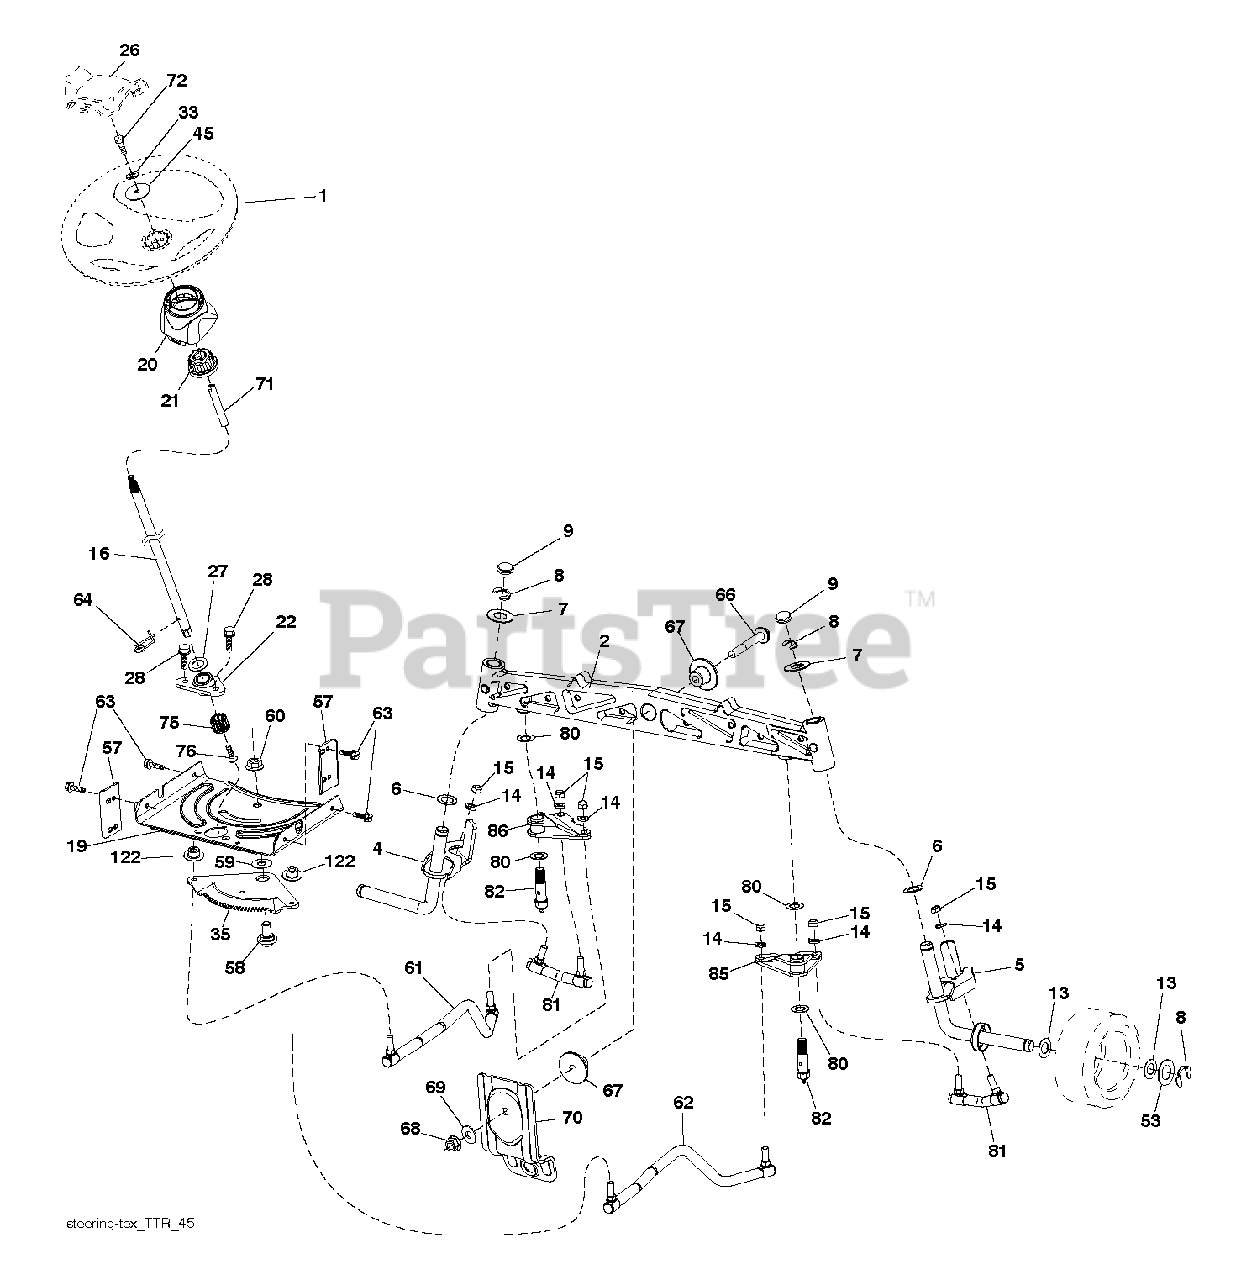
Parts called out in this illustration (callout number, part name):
1	WHEEL.STEER.HUSQ.SR.498.OVMLD
2	AXLE ASSY;TTR;ALUMINUM SILVER
4	SPINDLE WELDMENT.SPINDLE.LH.15
5	SPINDLE WELDMENT.SPINDLE.RH.15
6	THRUST WASHER
9	CAP.SPINDLE.BLACK
14	WASHER, LOCK 3/8
15	NUT CROWNLOCK 3/8-24
16	3 HIGH.SHAFT-ZINC.PLATED
19	PLATE.STEER.DDL.NLT/NG
20	STEERING.BOOT.HUSQ.LT
21	RP STEERING.WHEEL.ADAPTER
22	BEARING.SUBASM.SHAFT.STEER.LOW
26	INSERT.CAP.WHL.STRG.HUSQ.PREM
28	SCREW, 3/8-16X3/4
33	LOCKWASHER
35	GEAR GEAR.SECTOR.TEX.NZTR
45	WASHER.11/32
53	WASHER.HARDENED
57	BRACKET.UPSTOP.TEX
58	BOLT.SHOULDER.SECTOR.P
59	WASHER.THURST.SECTOR.S
60	NUT FLANGE LOCK 5/8-11
61	LINK ASSY DRAGLOINK, ADJUSTABL
62	DRAGLINK,ADJUSTABLE,RH
63	SCREW
64	RETAINER.CLIP.SPRING.S
66	BOLT HEX FGHD 7/16-14 X 3 SERR
67	BUSHING.PM.FRONT AXLE
68	NUT.LOCK.FLANGE.7/16
69	WASHER.1.5X.505X.118
70	BRACKET.FRT.DECK.SUSP.RR.MT431
71	SHAFT.EXTEN.STRG.SPLINE
72	BOLT 5/16-18 X 4 W/PATCH
75	PINION.ZINC PLATED
76	SCREW HEAD SOCKET LRVB
80	THRUST WASHER
81	LINK SUBASM.LINK.CROSS.NZTR
82	SUBASM;PIVOT;BOLT;NZTR
85	PIVOT SUBASM.PIVOT.RH.NZTR
86	PIVOT SUBASM.PIVOT.LH.NZTR
122	CAP.GEAR.SECTOR.TEX
